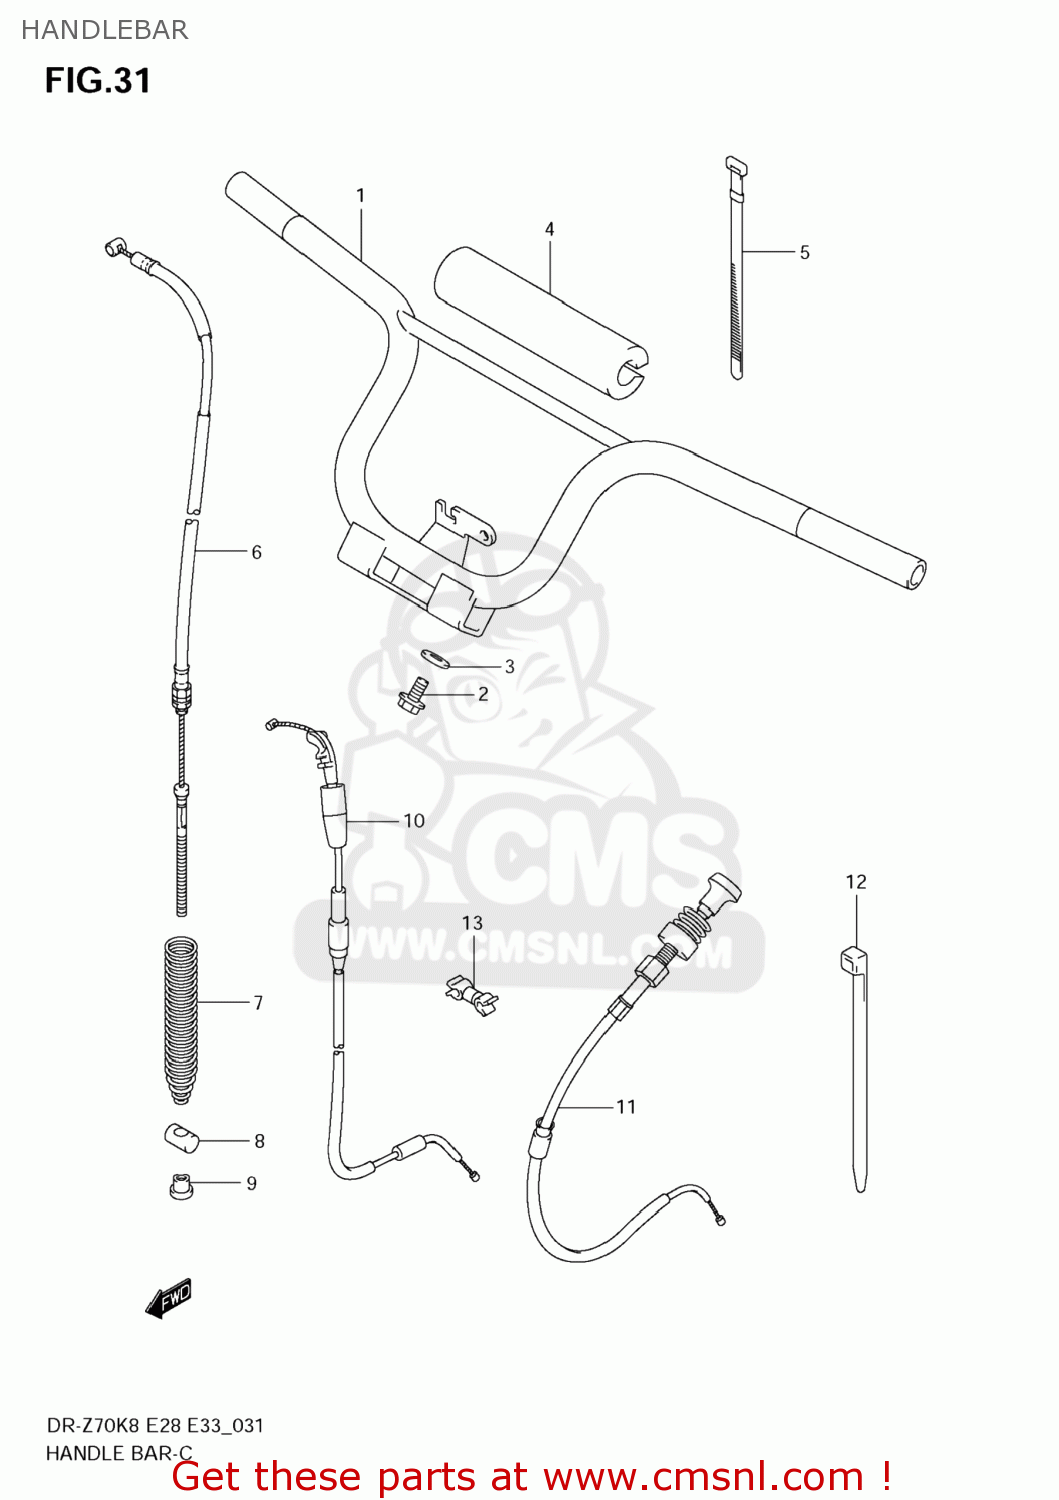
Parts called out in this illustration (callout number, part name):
1	HANDLEBAR(SILVER)
2	BOLT
3	WASHER(8.5X22X2)
4	PAD,CROSS BAR
5	CLAMP
6	CABLE,FR BRAKE
7	SPRING,FR BRAKE CABLE
8	PIN(11X18)
9	NUT
10	CABLE ASSY,THROTTLE
11	CABLE ASSY,STARTER
12	CLAMP(L:100)
13	CLAMP
